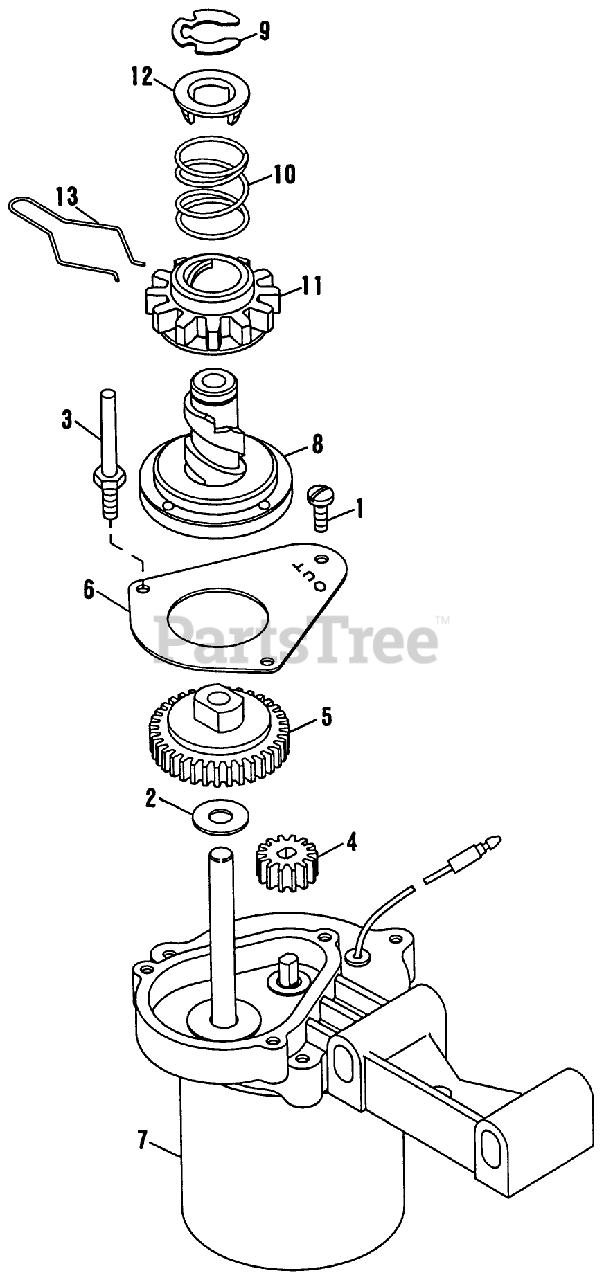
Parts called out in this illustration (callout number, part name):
1	SCREW EF
4	PINION SM
6	GEAR COVER EF
9	RET.RING EF
10	*SPRING PINION EF
11	PINION SM
12	STOP WASHER EF
13	SPRING - DRAG
